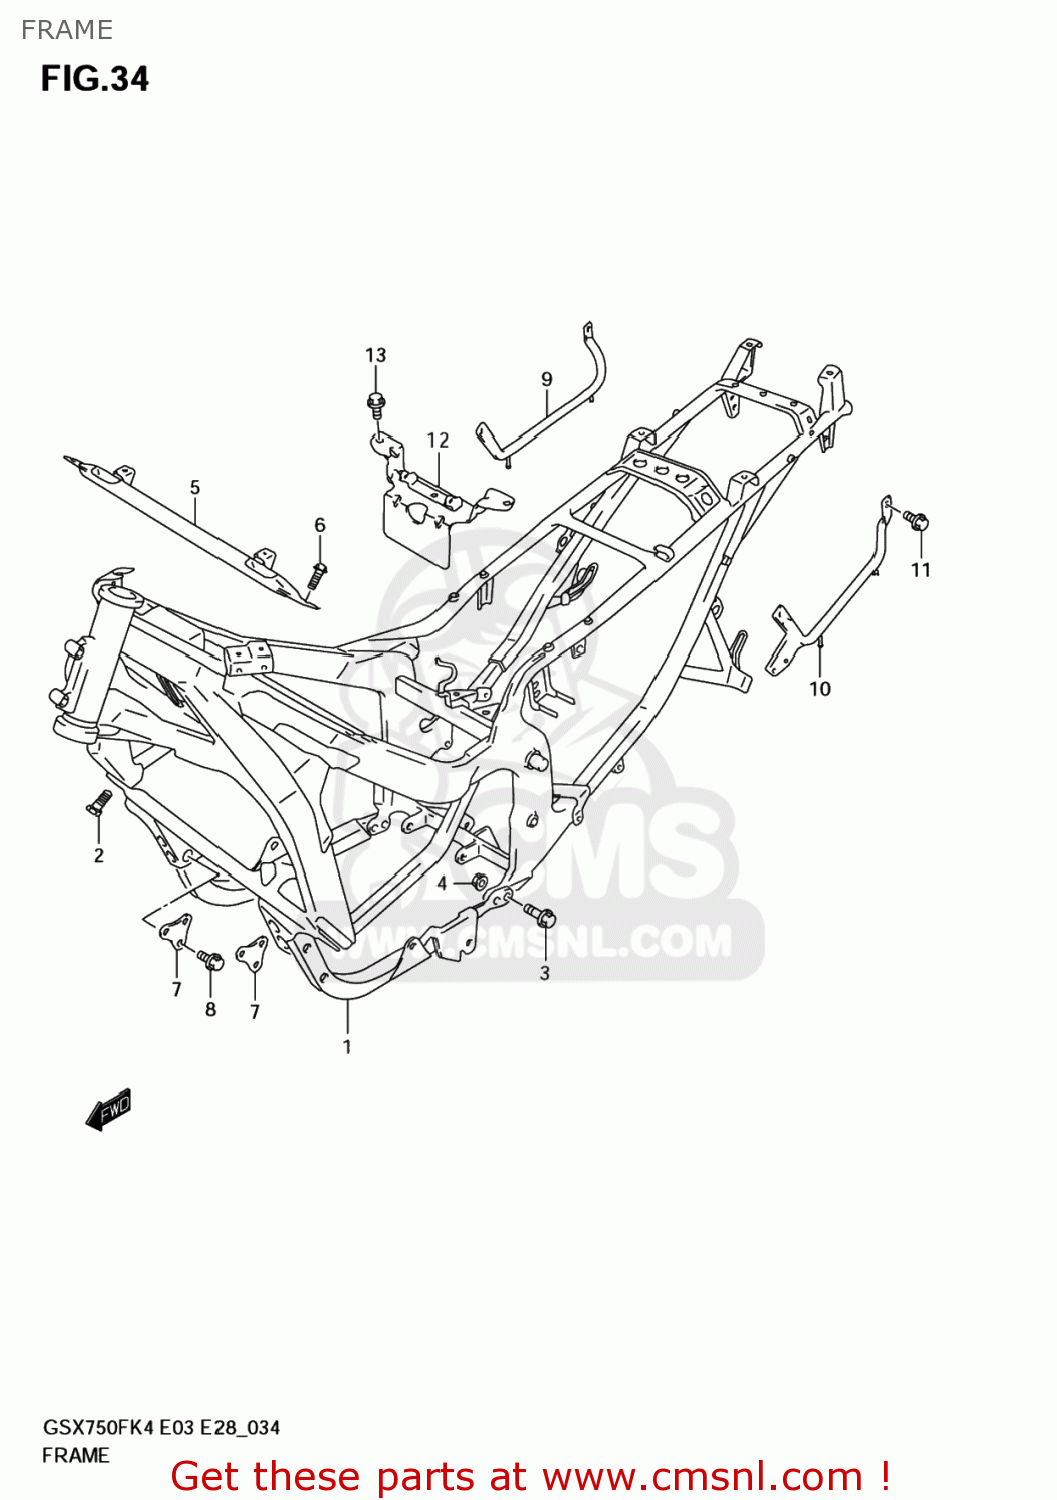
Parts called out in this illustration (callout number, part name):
1	FRAME(BLACK)
2	BOLT
3	BOLT
4	NUT
5	TUBE,FRAME BRIDGE NO.2
6	BOLT(8X20)
7	PLATE,ENG MTG NO.1
8	BOLT, UPPER
9	GRIP,RR,R
10	GRIP,RR,L
11	BOLT
12	PLATE,ELECTRIC PARTS HOLDER
13	BOLT
